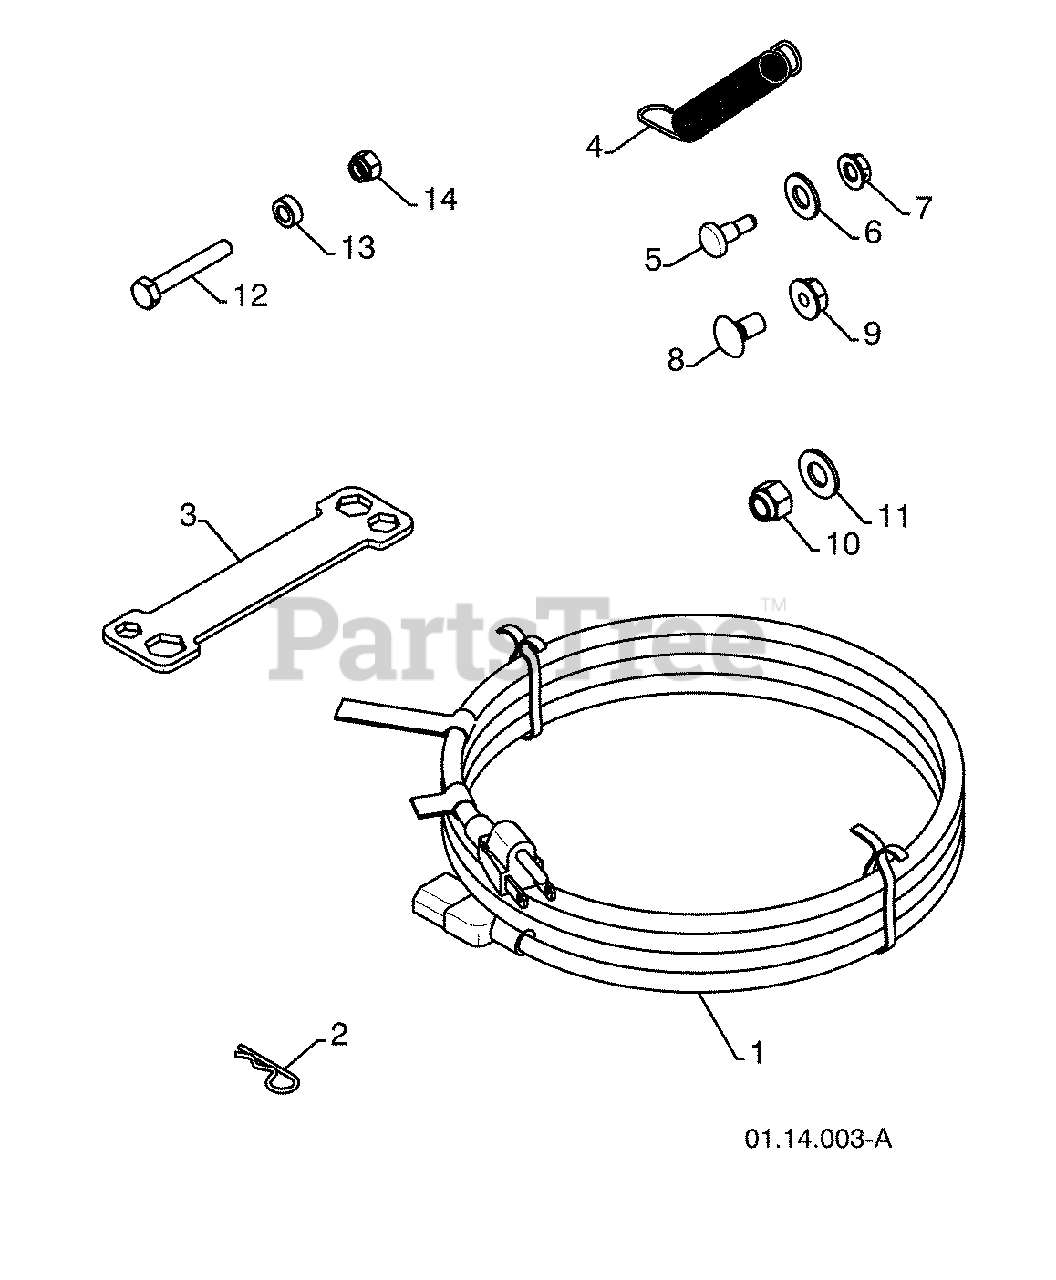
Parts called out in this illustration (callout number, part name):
1	POWER CORD
2	RETAINER PIN
3	WRENCH
4	REMOTE SPRING
5	SHOULDER BOLT 1/4-20
6	NYLON WASHER 1/4-20
7	LOCKNUT 1/4-20
8	CARRIAGE BOLT 5/16-18 X 5/8
9	LOCKNUT 5/16-18
10	LOCKNUT 3/8-16
11	WASHER 3/8
12	SHEAR BOLT 1/4-20 X 1-3/4
14	LOCKNUT 1/4-20
